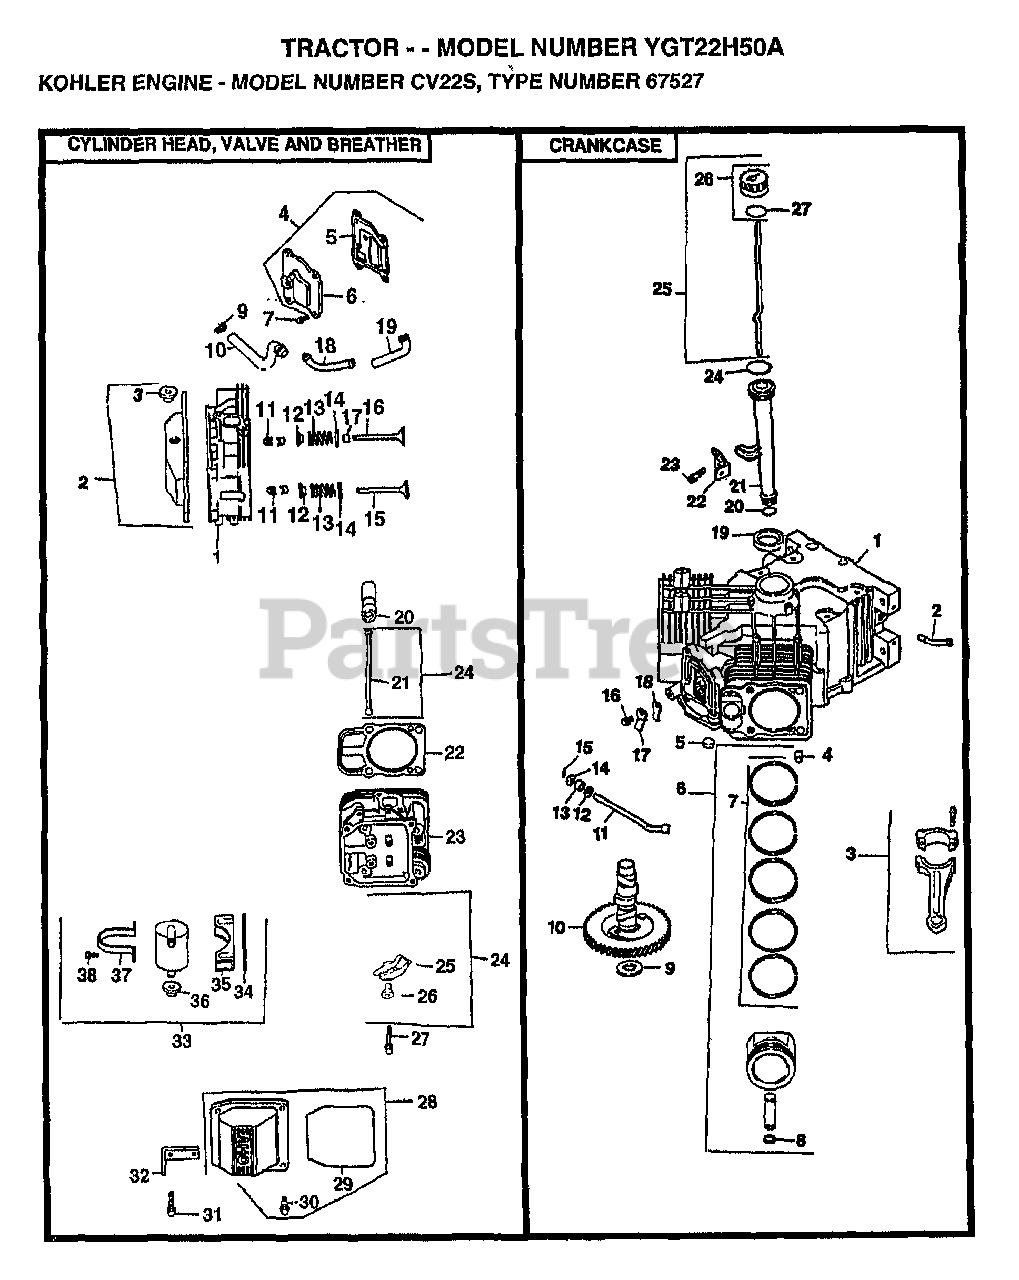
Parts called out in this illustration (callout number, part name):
1	HEAD ASSEMBLY
1	MINIBLOCK
2	KIT, VALVE COVER, BREATHER
2	FITTING
3	GROMMET, RUBBER
3	CONNECTING ROD
3A	CONNECTING ROD
4	KIT, BREATHER COVER W/GASKET
4	PIN, DOWEL LOCATING
5	GASKET, BREATHER
5	PLUG, CUP
6	COVER, BREATHER
6	PISTON WITH RING SET
6A	PISTON WITH RING SET
6B	PISTON WITH RING SET
7	SCREW HEX FLANGE
7	RING SET
7A	RING SET
7B	RING SET
8	RETAINER, PISTON PIN
9	CLAMP, HOSE
9	SHIM, CAMSHAFT, YELLOW
9A	SHIM, CAMSHAFT,RED
9B	SHIM, CAMSHAFT, BLACK
9C	SHIM, CAMSHAFT, WHITE
9D	SHIM, CAMSHAFT, BLUE
9E	SHIM, CAMSHAFT, GREEN
9F	SHIM, CAMSHAFT, GREY
10	HOSE, BREATHER
10	CAMSHAFT
11	KIT, RETAINER
11	SHAFT, GOVERNOR CROSS
12	CAP, VALVE SPRING
12	WASHER, PLAIN
13	SPRING, VALVE
13	SEAL ,GOVERNOR CROSS SHAFT
14	RETAINER, SPRING
14	WASHER
15	VALVE, EXHAUST, STANDARD SIZE
15	PIN
15A	VALVE, EXHAUST, .25 OVERSIZE
16	VALVE, INTAKE, STANDARD SIZE
16	SCREW, MOUNTING
16A	VALVE, INTAKE, .25 OVERSIZE
17	SEAL, VALVE STEM
17	RETAINER, REED
18	FITTING
18	REED, BREATHER
19	HOSE, BREATHER
19	SEAL, OIL, FRONT
20	LIFTER, VALVE
20	O-RING, LOWER OIL FILL TUBE
21	ROD, PUSH
21	TUBE, OIL FILL
22	GASKET, CYLINDER HEAD
22	BRACKET, OIL FILL TUBE
23	HEAD ASSEMBLY
23	SCREW
24	KIT, VALVE TRAIN
24	O-RING, UPPER OIL FILL TUBE
25	ARM, ROCKER
25	DIPSTICK ASSEMBLY
26	PIVOT, ROCKER ARM
26	KIT OIL FILL CAP
27	SCREW, ROCKER ARM
27	O-RING, DIPSTICK
28	KIT, VALVE COVER, PLAIN
29	O-RING
30	SCREW
31	SCREW
32	STRAP LIFTING
33	KIT, BREATHER SEPARATOR
34	SPACER
35	BRACKET, BREATHER SEPARATOR
36	GROMMET, RUBBER
37	STRAP, BREATHER SEPARATOR
38	SCREW
